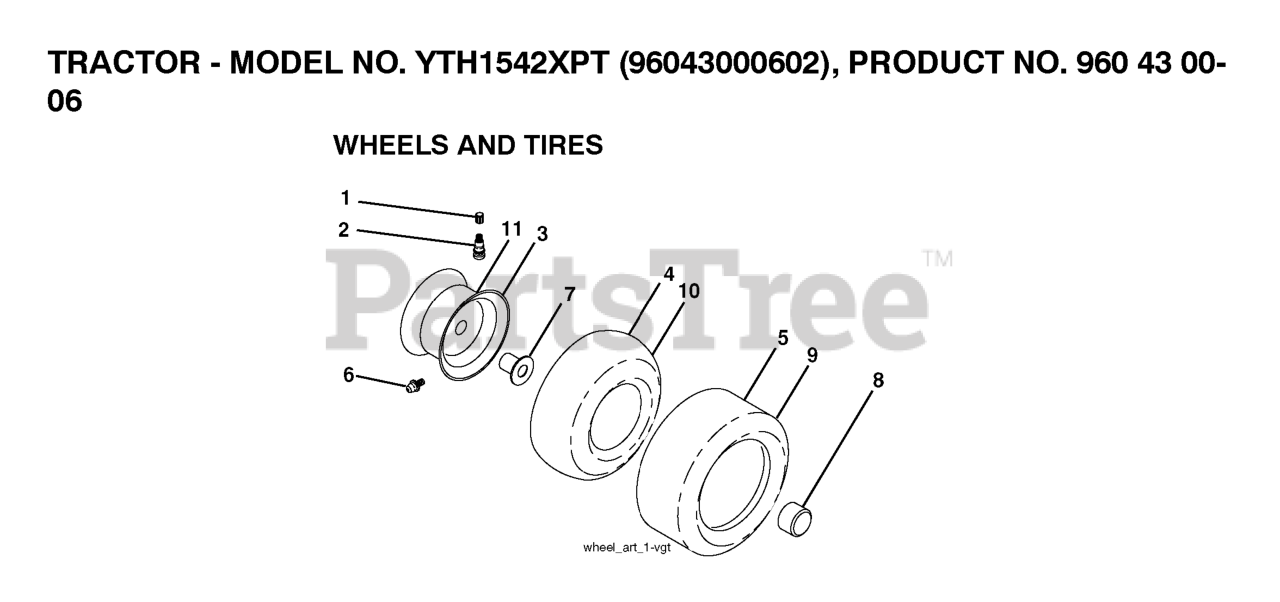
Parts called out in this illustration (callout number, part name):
2	VALVE STEM LT
3	RIM ASM 6" FRONT SILVER
4	TUBE.16X6.5/7.5-8
5	TIRE HEAVY DUTY
6	FITTING LT.
7	BEARING.FLANGE
8	CAP, AXLE BLK
9	TIRE.TS.20X10-8
10	TUBE.23X9.5-12
11	RIM ASM 8" REAR SILVER
